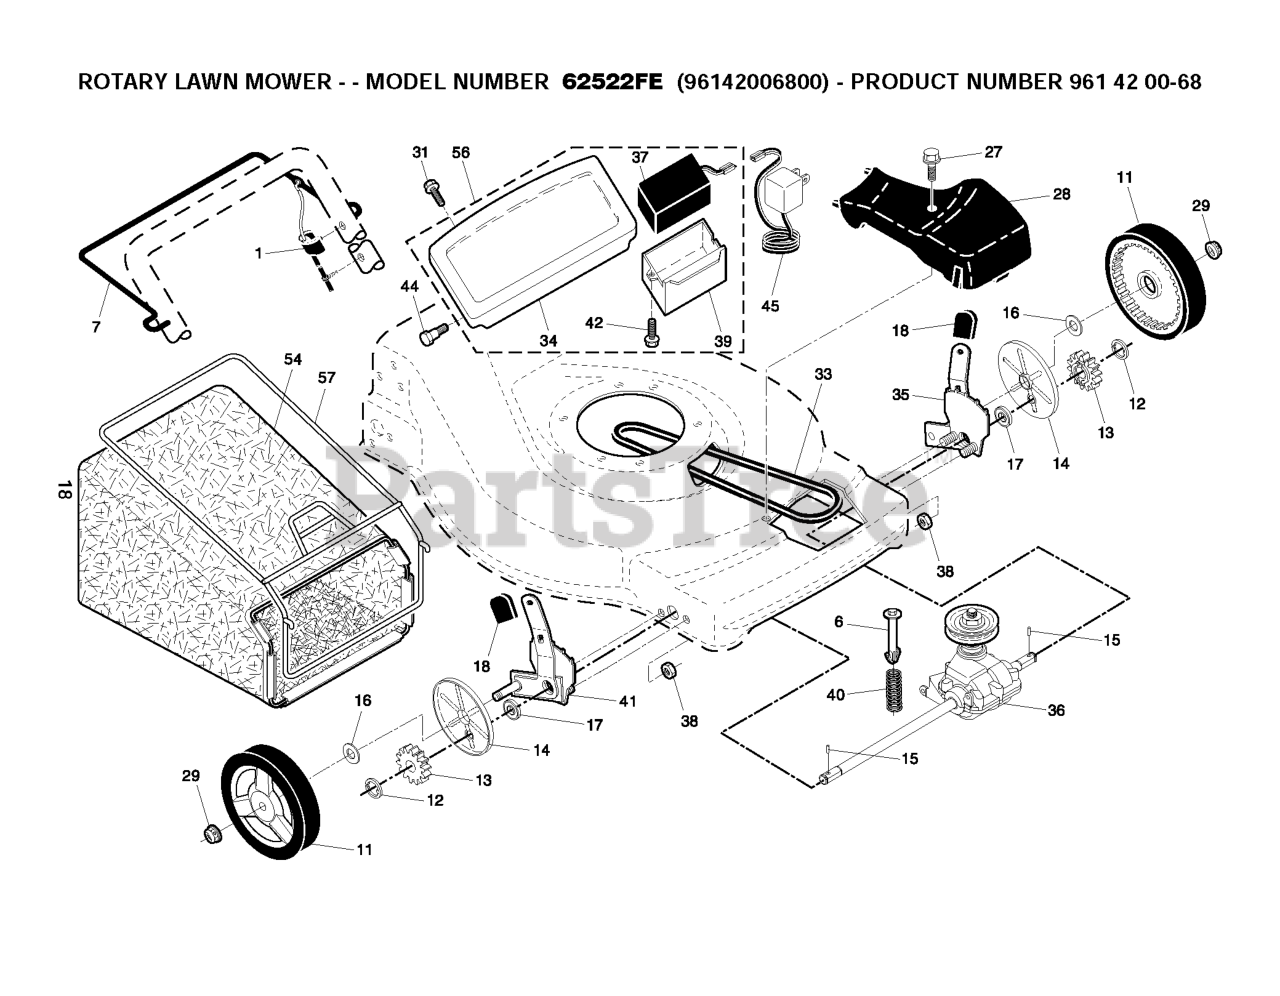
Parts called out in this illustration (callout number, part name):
1	CONTROL.DRIVE.S/SPEED.FWGD
6	SPRING RETAINER
7	BAIL.CONT.DR.S/S.ROUND.ORG
11	WHEEL.8X1.75.H3SPK.RAD3.GY.BU3
12	E-RING 7/16 RE
13	PINION.14.TEETH.FGD
14	COVER.DUST.WHEEL
15	PAWL, DRIVE
16	WASHER FLUT
17	BEARING
18	SELECTOR KNOB
27	SCREW, HEX HD TAPPING #10-24 1
28	COVER.DRIVE.TORUS.B&S.MOLDED
29	NUT.HEX.FLANGE.3/8-16.LO(3 2)
31	SCREW.PAN.HEAD.#10
33	BELT THERM .32
34	PANEL.TRIM.21.FWGD.ES
35	RP KIT, WHEEL ADJUSTER, LH
36	TRANSMISSION.22.FGD/W/PULLEY
37	BATTERY WITH AMP CONECTOR AGM
38	LOCKNUT.NYLOC.1/4-20
39	BOX.BATTERY.TRIM
40	SPRING.EXTENSION
41	KIT, WHEEL ADJUSTER, RH
42	SCREW.HWH.13-16X.50
44	SCREW.SHOULDER.HH.10X.281X.6
45	RP CHARGER.BATTERY
54	GBAG.83230247T.SIL.HUSQ.BLU
56	PANEL.ASM.TRIM/BATTERY.BOX
57	FRAME.GBAG.22.EZ.EMPTY.SC
